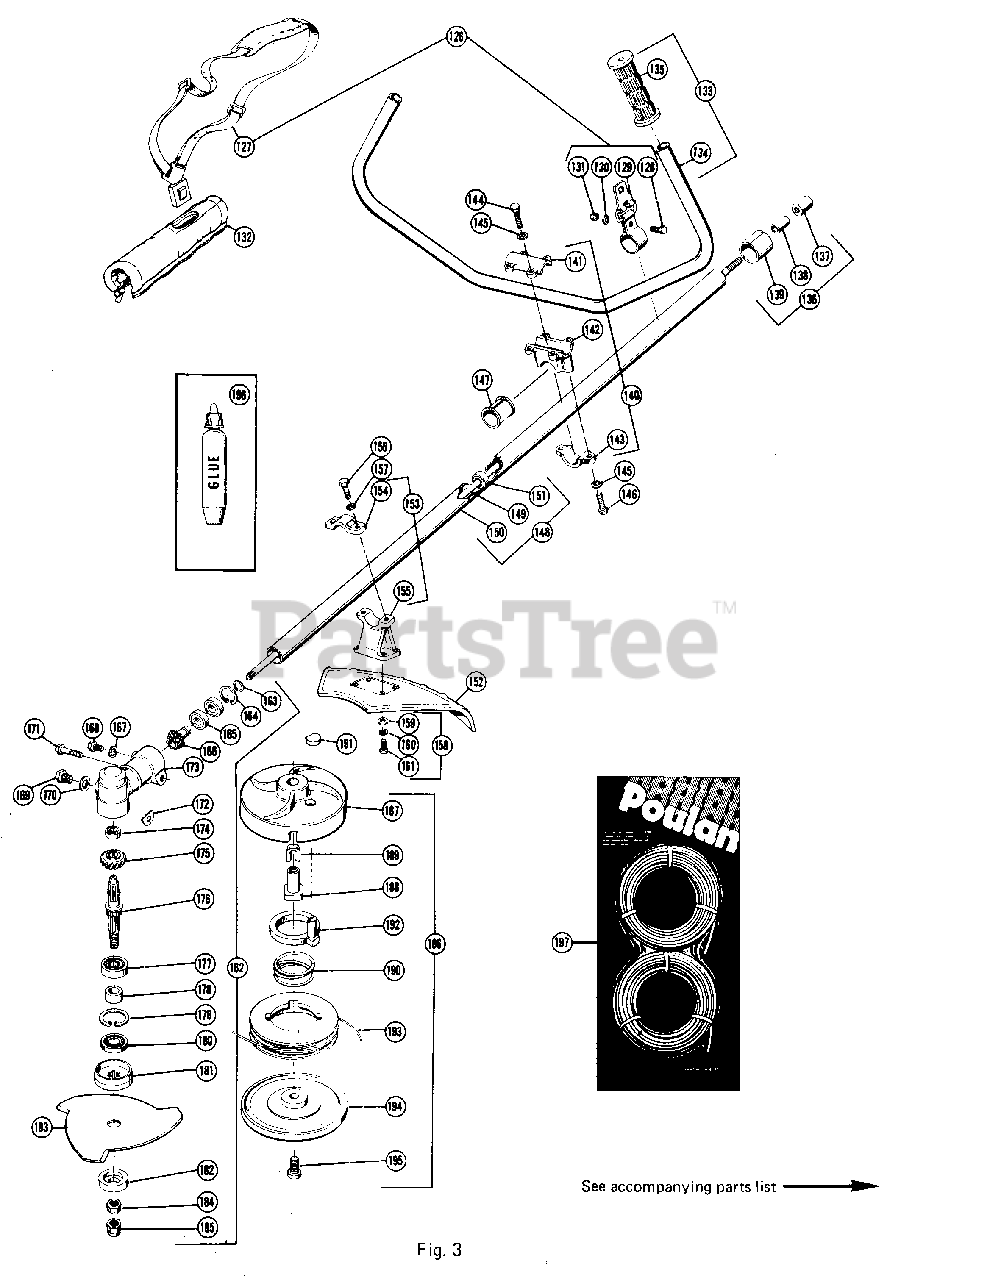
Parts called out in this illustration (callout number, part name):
126	Shoulder strap assembly (inc.127-131)
133	Handle bar assembly (inc.134-135)
134	Handle bar
136	Drive shaft adapter kit (inc.137-139)
137	Drive shaft
138	Drive shaft adapter screw
139	Drive shaft adapter spacer
140	Handle bar clamp assembly (inc.141-143)
141	Handle bar clamp top
142	Handle bar clamp middle
143	Handle bar clamp bottom
144	Bolt, top
146	Bolt, bottom
147	Spacer, bar clamp
148	Drive shaft housing complete (inc.149-151)
149	Drive shaft
150	Drive shaft housing
153	Shield mounting bracket ass'y (inc.154-155)
154	Shield mounting bracket top
155	Shield mounting bracket bottom
158	Shield mounting kit (inc.159-161/4 each)
159	Washer, flat
160	Washer, lock
162	Transmission ass'y (inc.163-185/except 183)
163	Snap ring, gear housing
164	Snap ring, gear housing bearing
165	Bearing, pinion gear
166	Pinion, gear
167	Lock washer, housing bolt
169	Oil hole plug
171	Housing bolt
172	Fiber-filler washer
173	Housing, gear box
174	Bearing, gear box
175	Gear, bevel
177	Ball bearing
178	Collar, shaft
179	Snap ring
180	Oil seal
181	Gear housing upper plate
182	Gear housing lower plate
183	Tri-cut blade
184	Nut, plate
186	Cutting head assembly (inc.187-195)
188	Drive adapter
189	Line saver
191	Button-release
192	Lock ring, cutting
193	Spool, w/line
194	Cover, cutting head
195	Cover screw
197	Cutting line skin pak
